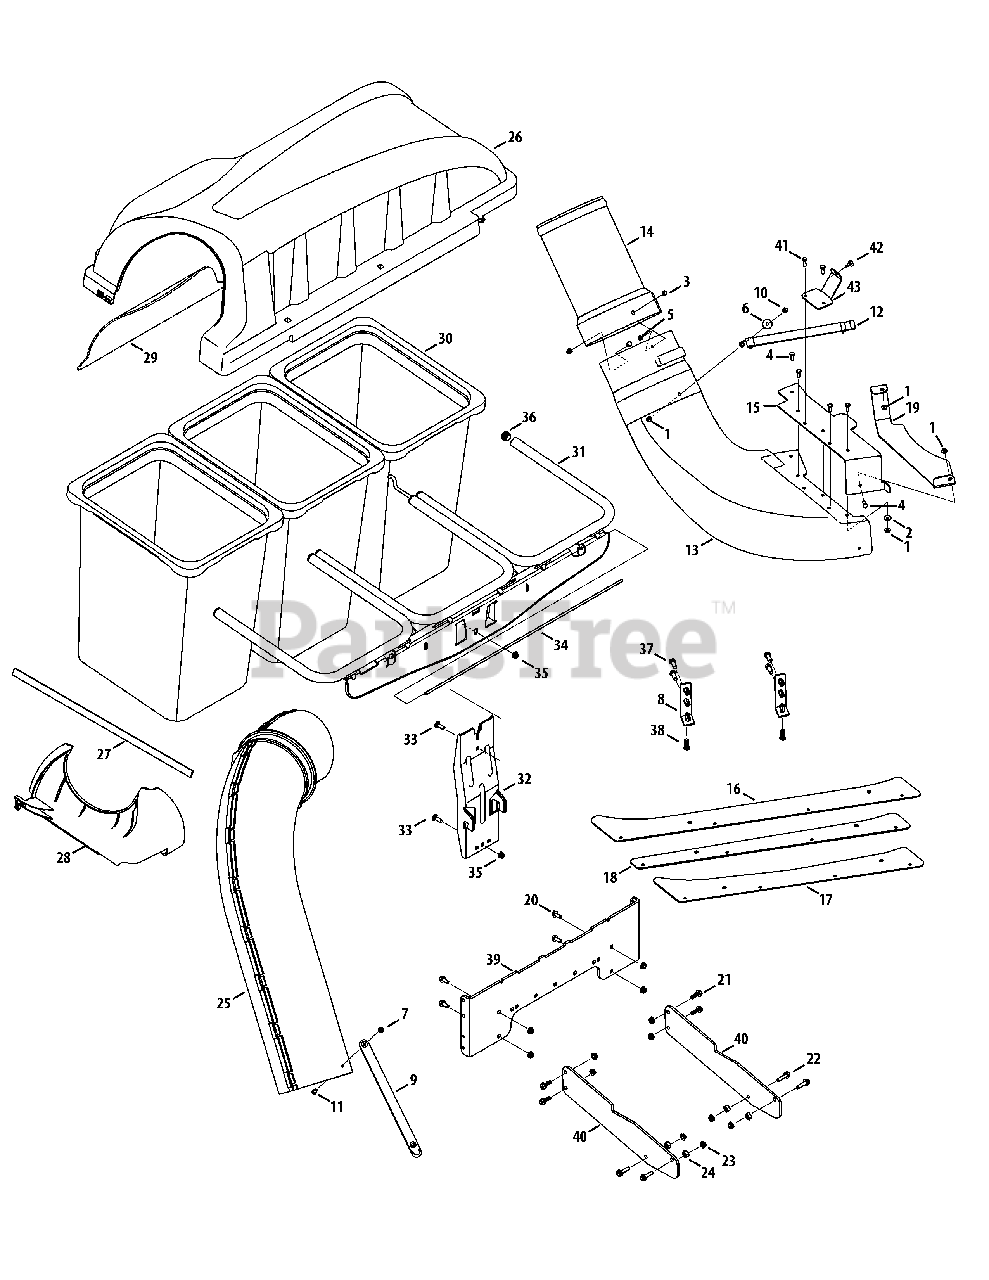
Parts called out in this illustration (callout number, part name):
1	Hex Flange Nut, 1/4-20
2	SPRING WASHER BELL
3	Cap Lock Nut, 1/4-20
4	SCREW 1/4-20 x .620 GR5
5	Hex Head Screw, 1/4-20 x .50
6	Flat Washer, .265 x 1.0 x .030
7	Flange Lock Nut, 1/4-20
8	Bagger Bracket Assembly
9	Chute Strap, 11.65" Lg.
10	Grass Catcher Pin, 1/4-20
11	Machine Screw, 1/4-20 x 0.750
12	Chute Strap
13	Discharge Chute Elbow
14	Bagger Chute Adaptor
15	Bagger Mounting Bracket
16	Front Baffle, 60"
17	Front Baffle, 48"
18	Front Baffle, 54"
19	Inner Boot Bracket
20	Hex Flange Screw, 5/16-18
21	Hex Flange Screw, 5/16-18 x 1.0
22	Hex Flange Screw, 5/16-18 x 1.25
23	HEX FLANGE NUT
24	Hex Nut, 5/16-18
25	Upper Chute Assembly
26	Triple Bagger Cover Assembly
27	Adhesive Foam Strip
28	Upper Chute Support
29	Bagger Cover Screen
30	Grass-bag Assembly
31	Triple Bag Support Assembly
32	Vertical Support Bracket
33	Carriage Screw, 5/16-18 x 1.00"
34	Cover Hinge Pin
35	Flange Lock Nut, 5/16-18
37	Hex Screw, 3/8-16 x 1.00
38	Hex Screw, 3/8 x 16 Low Profile
39	Cross Support Bracket
40	Side Support Brackets
41	Hex Head Screw, 1/4-20 x .75
42	Rubber Bumper
43	Chute Support Bracket
